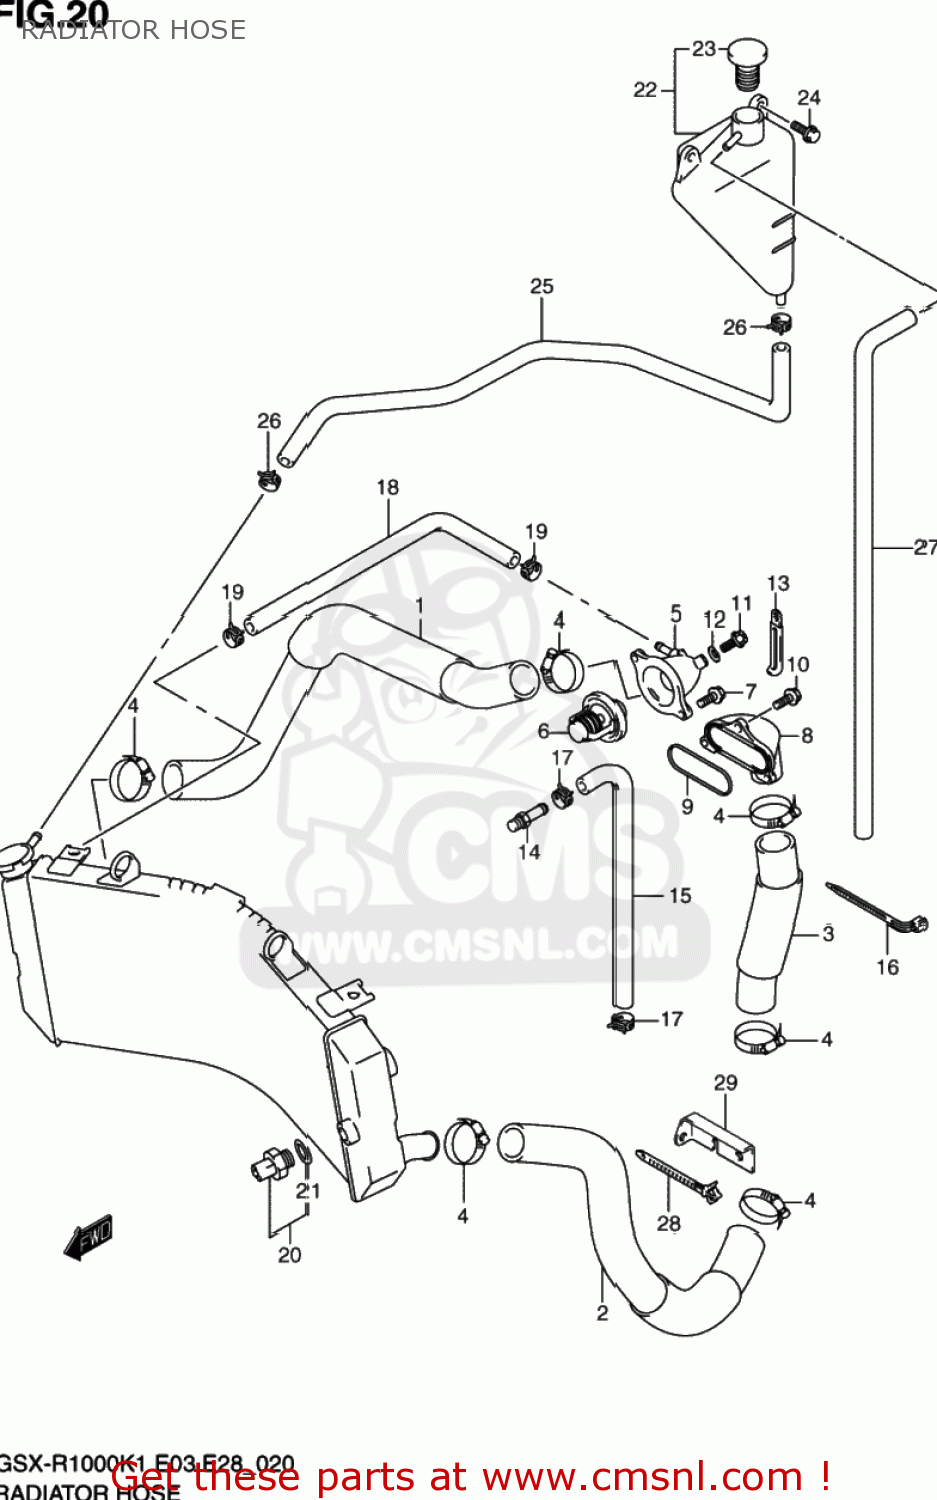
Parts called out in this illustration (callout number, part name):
1	HOSE,RADIATOR INLET
2	HOSE,RDTR OUTL
3	HOSE,CYLINDER
4	CLAMP
5	COVER,THERMOSTAT
6	THERMOSTAT,WATER 82 DEG
7	SCREW
8	CONNECTOR,CYL.
9	O RING,CYL WATER CONNECTOR
10	SCREW
11	UNION BOLT,AIR VENT
12	GASKET(6.4X11.5X0.8) (NAS)
13	CLAMP(L:65)
14	BOLT UNION
15	HOSE,WATER BYPASS
16	CLAMP(L:165)
17	CLAMP
18	HOSE(5X11X600)
19	CLIP
20	SWITCH,RADIATOR FAN
21	O-RING
22	TANK ASSY,RESERVOIR
23	CAP,RESERVOIR TANK
24	BOLT
25	HOSE,RESERVOIR TANK INLET
26	CLIP
27	HOSE(5X9X600)
28	CLAMP
29	BRACKET,HOSE CLAMP
